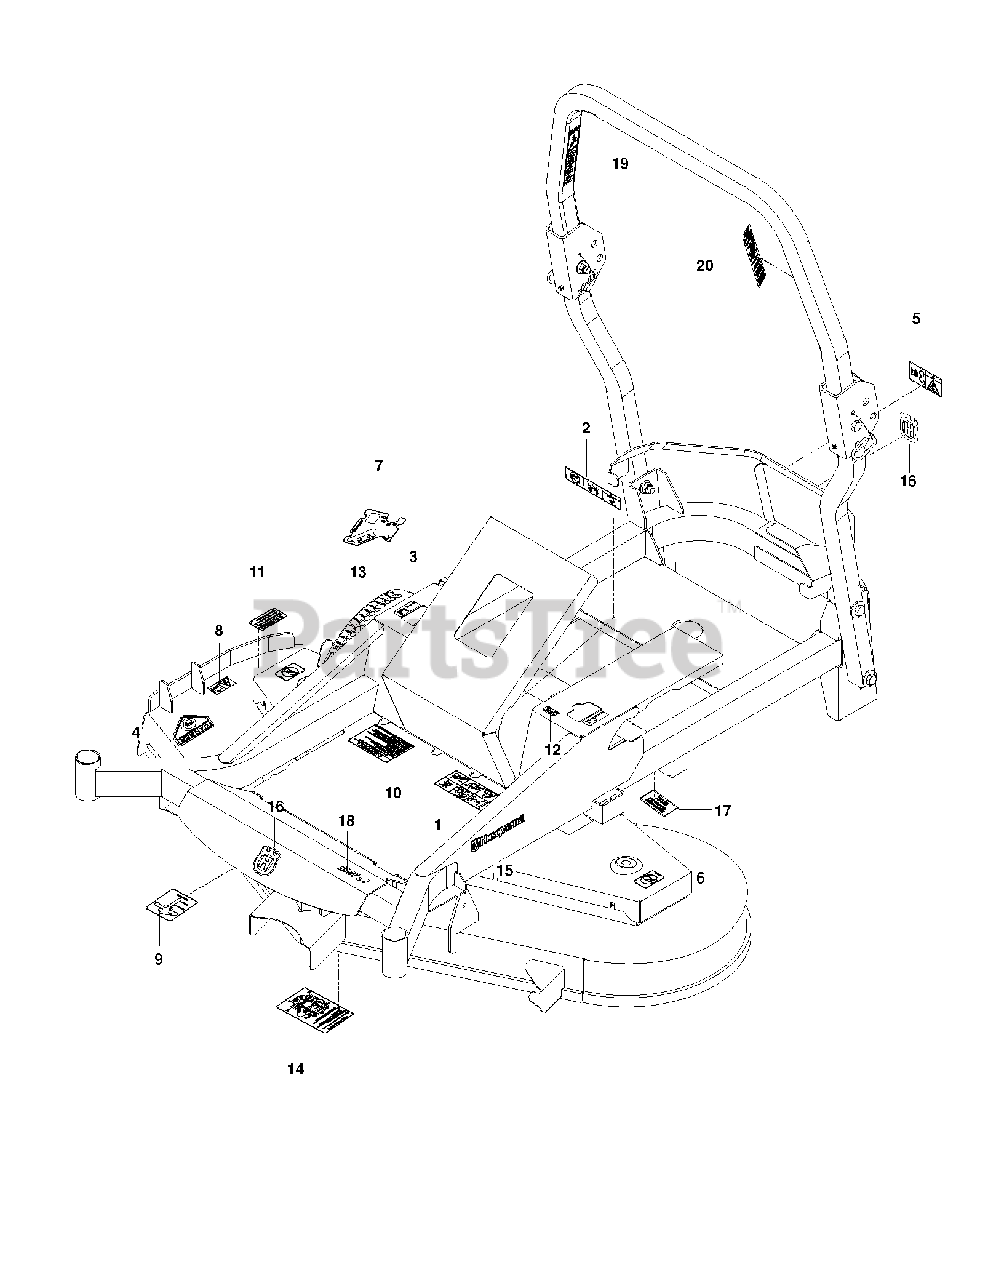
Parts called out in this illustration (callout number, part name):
1	DECAL, WARNING
2	EURO DECAL-BATTERY WARNIN6
3	DECAL, MOTION CONTROL
4	DECAL, CPSC
5	DECAL, BELT DRIVE
6	DECAL, NO STEP
7	DECAL, CONSOLE
8	DECAL, EURO SEVERING
9	DECAL, BELT ROUTING
10	DECAL, WARNING
11	DECAL, CAUTION
12	DECAL, F.S.T.
13	DECAL, HEIGHT ADJUST
14	DECAL, SERVICE
15	RP.DECAL.BADGE.170MM.TEXTLOGO
16	DECAL.AUGER.HUSQ.CROWN.SNOW
17	DECAL ZTR MZT61 HUSQVARNA
18	DECAL, MZ6128
19	DECAL, ROPS, WARNING
20	DECAL ROPS
